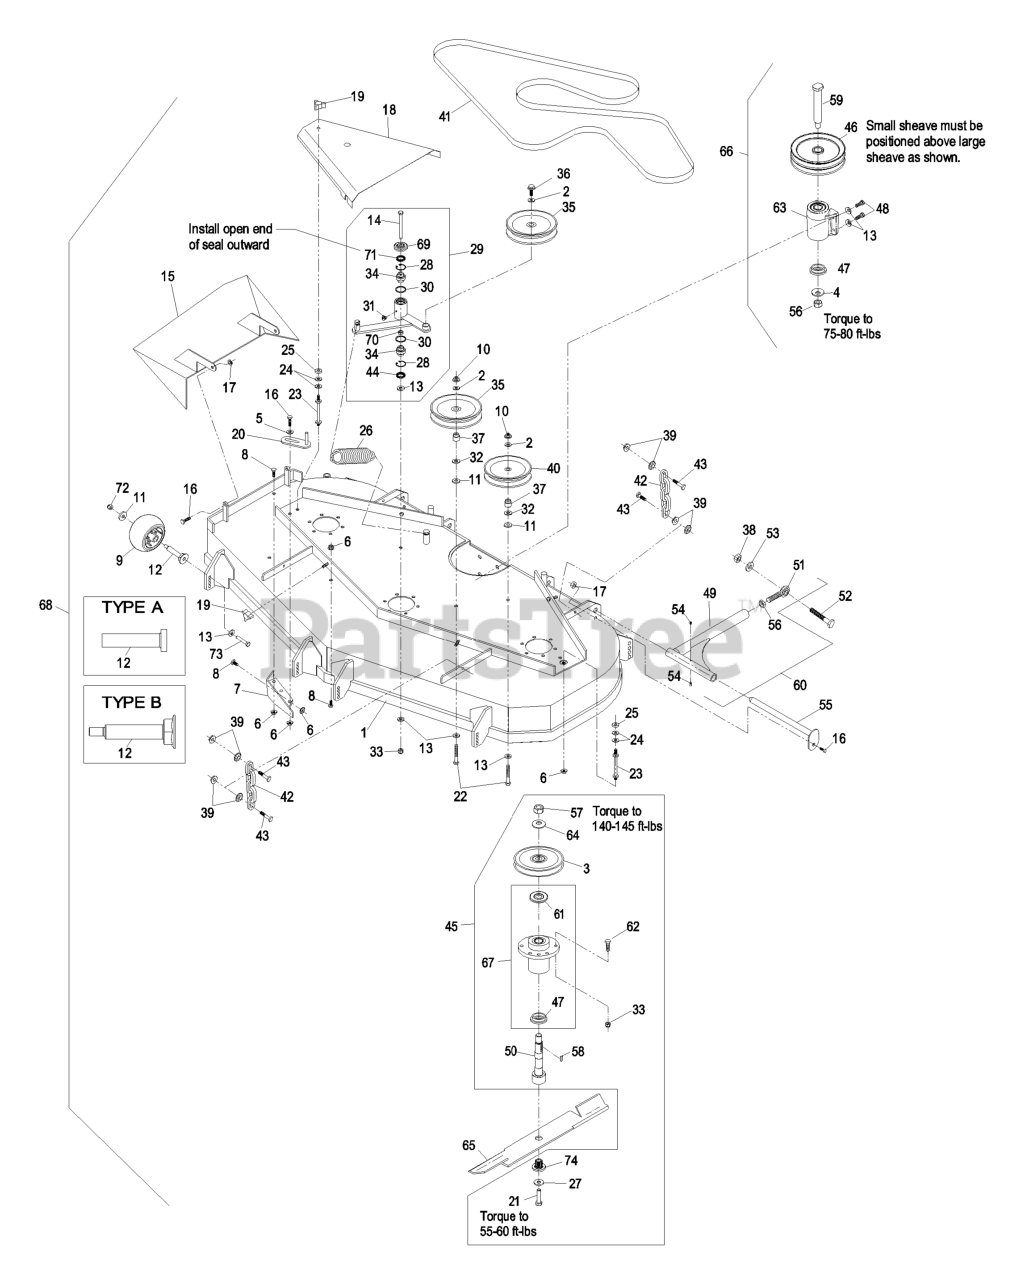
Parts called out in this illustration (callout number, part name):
1	ASM,DECK W/DECALS LZ524
2	WASHER-FLAT
3	SHEAVE,BLADE DRIVE 6.30
4	WASHER-SPRING
5	WASHER-SPRING
7	WLD,BAFFLE DISCHARGE
8	SCREW-HH
9	ROLLER-SCALP, ANTI
10	NUT-HHF, WHIZ
12	BUSHING-ROLLER
13	WASHER-BELLEVILLE
14	SCREW-HH
15	WLD,CHUTE DICHARGE 524
16	SCREW-HH
17	NUT-LOCK, NI
18	SHIELD,BELT 52
19	KNOB-3 PRONG
20	GUIDE-BELT
21	SCREW-HH
22	SCREW-HH
23	STUD-SHIELD, BELT (SHORT)
24	WASHER-FLAT
27	WASHER-SPRING
28	RING-SNAP
29	KIT,DECK IDLER LZ/XP
31	FITTING-GREASE, 90 DEG
32	WASHER-FLAT
33	NUT-LOCK, NI
34	BEARING-SPHERICAL
36	SCREW-HHF
37	BUSHING-IDLER
38	NUT-HEX
40	PULLEY-IDLER
41	BELT,BLADE DRIVE 52
42	CHAIN-LIFT, DECK
43	SCREW-HH
44	SEAL-LIP, DOUBLE
45	ASM, CUTTER HSG COMPLETE
46	SHEAVE,JACKSHAFT - DBL
47	SPACER-GUARD, BOTTOM
48	SCREW-HH
50	KIT, SPLINED SPINDLE 103-
51	BALLJOINT-SPHERICAL
52	SCREW-HH
53	WASHER-LOCK
54	FITTING-GREASE
55	PIN-STRUT
56	NUT-HEX
57	NUT-HH
59	JACKSHAFT
60	STRUT ASM
61	GUARD-BEARING, TOP
62	SCREW-HH
66	KIT,JACKSHAFT 52-3750
67	KIT, CUTTER HOUSING
68	Asm, Deck Complete
69	GUARD-TOP
71	SEAL-LIP, SINGLE
72	NUT-HHF, WHIZ
73	SCREW-HH
74	BUSHING,SPLINED
